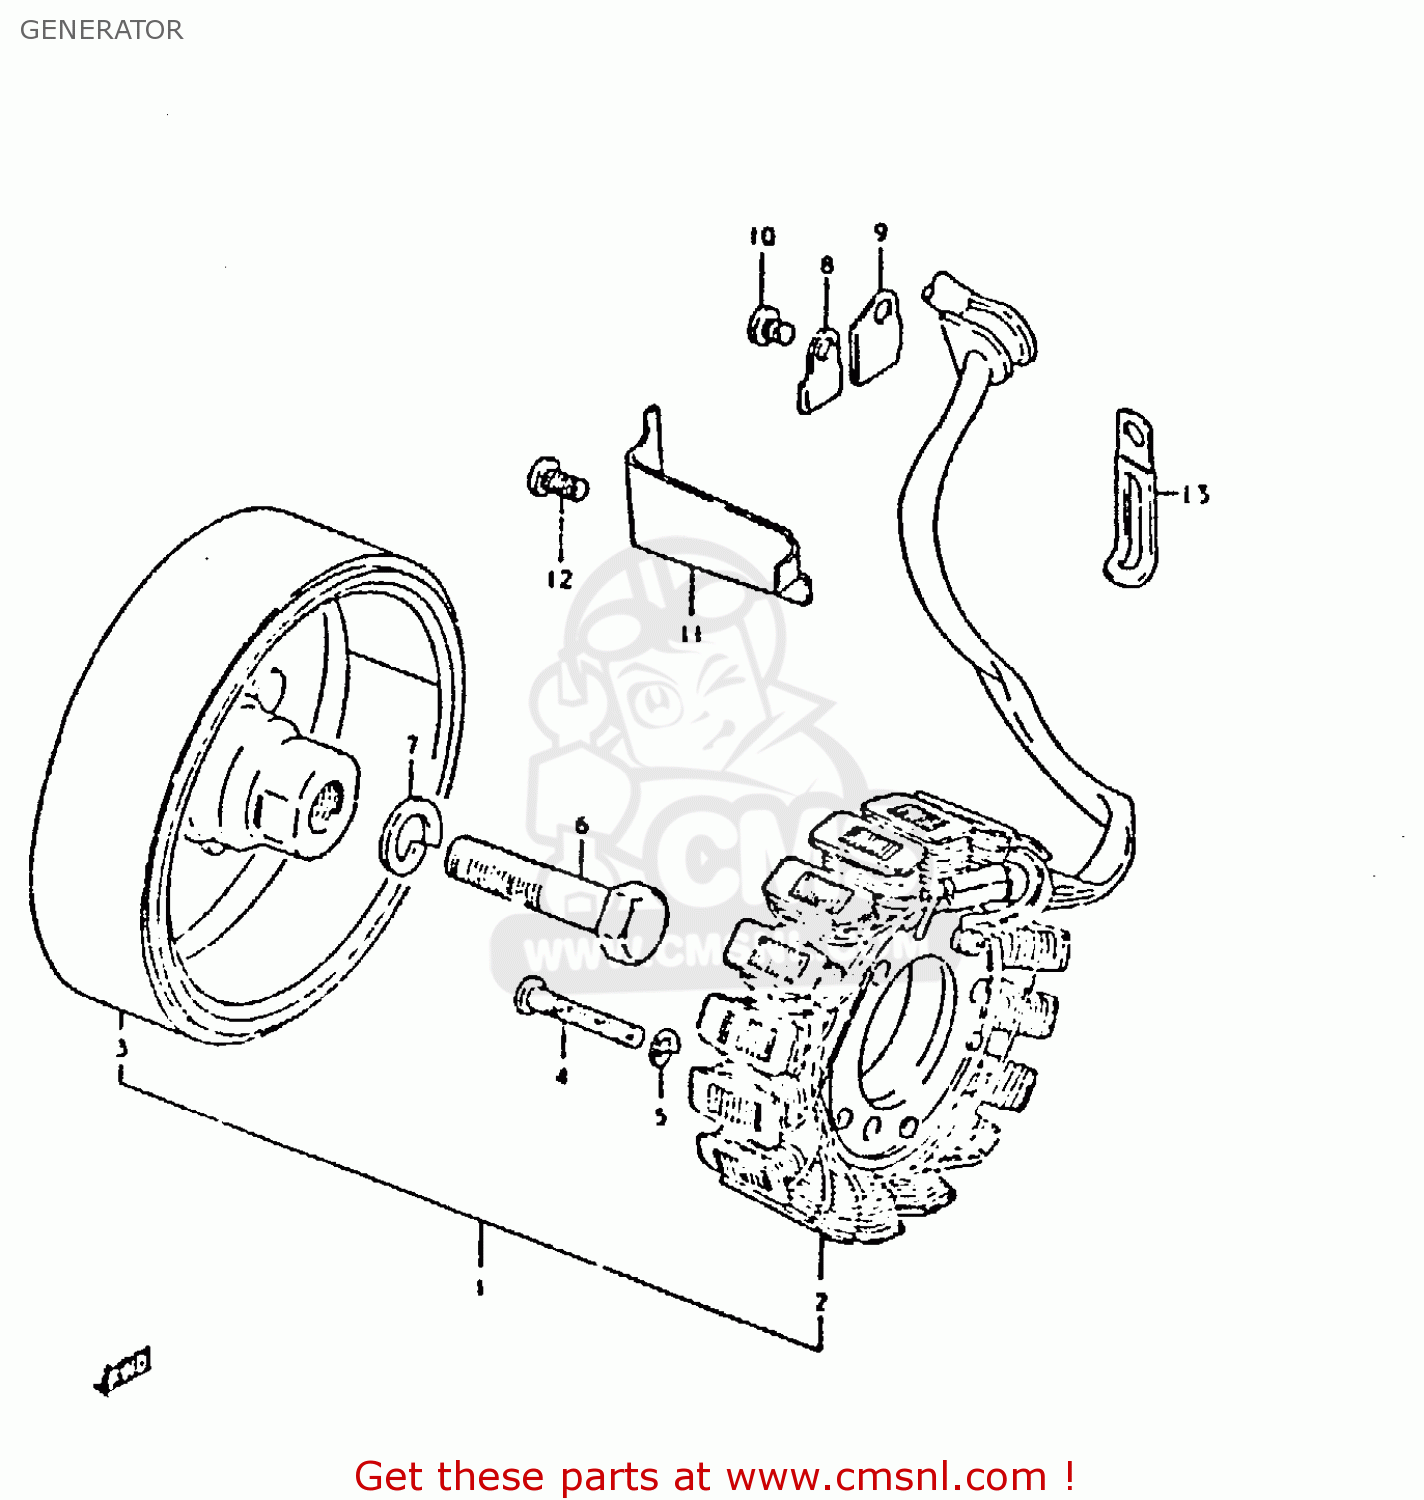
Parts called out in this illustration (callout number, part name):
1	GENERATOR ASSEMBLY
2	STATOR ASSEMBLY
3	ROTOR ASSEMBLY
4	SCREW
5	LOCK WASHER
6	BOLT 12X45
7	WASHER,LOCK 12
8	CLAMP,GENERATOR LEAD WIRE
9	CLAMP,GENERATOR LEAD WIRE
10	SCREW
11	CLAMP,GENERATOR LEAD WIRE
12	SCREW
13	CLAMP L:35
